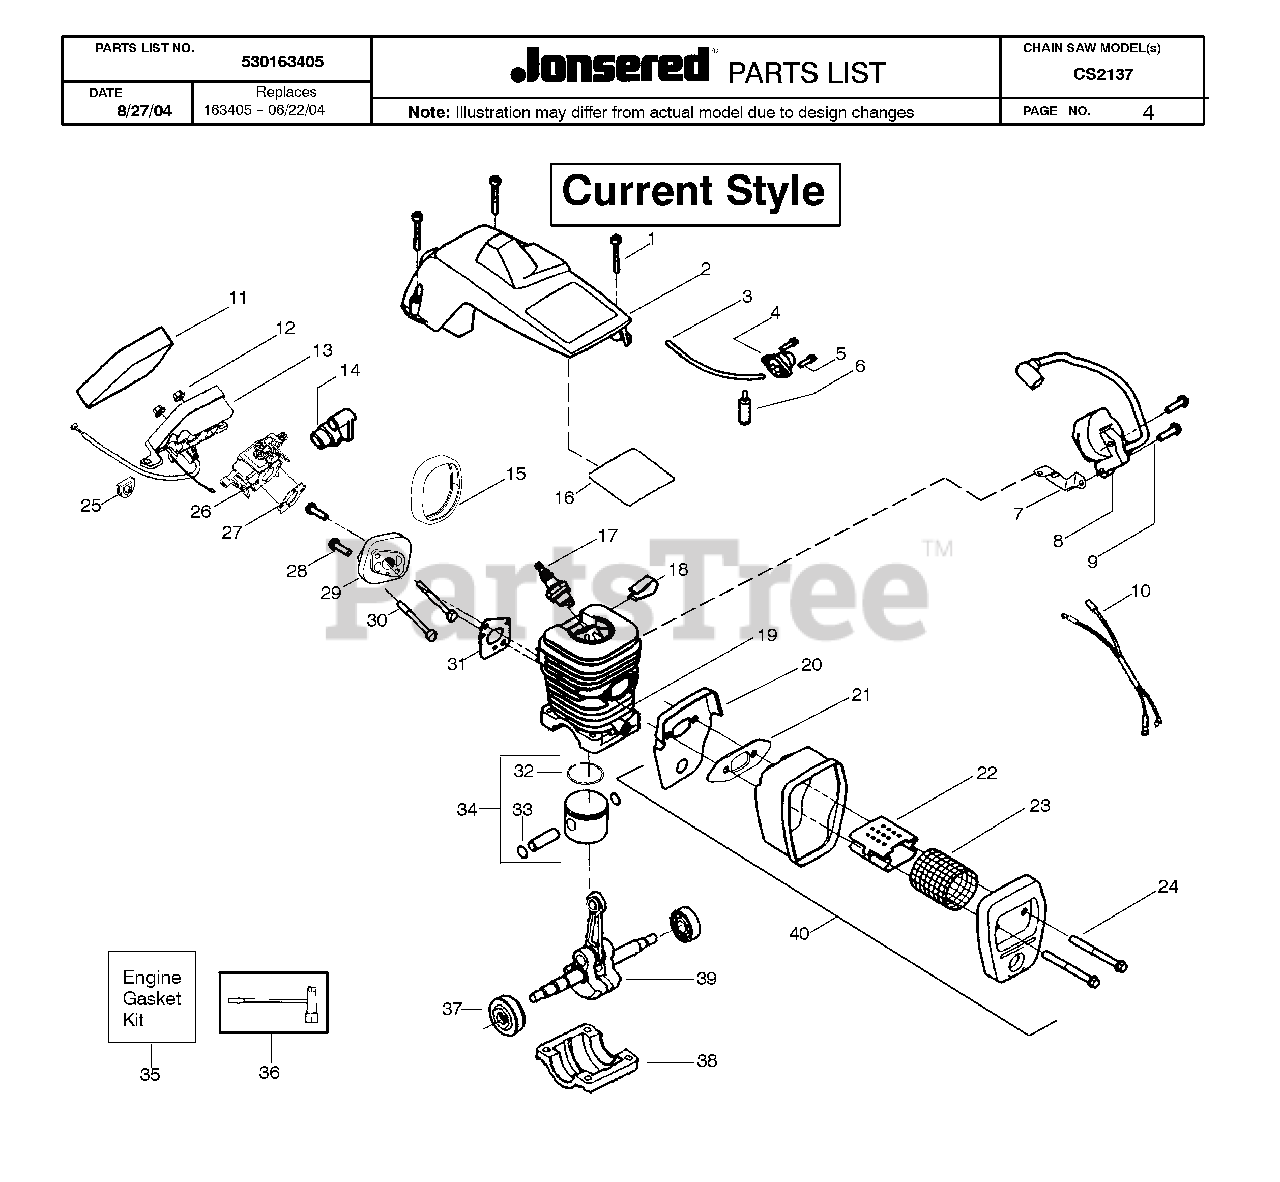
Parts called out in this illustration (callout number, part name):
2	CYL SHIELD ASSY
6	FUEL PICK-UP ASSY
7	GROUND STRAP
10	WIRE HARNESS ASSY
11	AIR FILTER
14	GROMMET-CARB ADJUST
17	SPARK PLUG (RCJ-7Y)
22	FLAME PROTECTION
29	PARTITION
32	RING-PISTON
33	C-CLIP,PSTN PIN 36/41
36	SCRENCH
37	BEARING & SEAL ASSEMBLY
39	CRANKSHAFT
40	MUFFLER
530071820	CARBURETOR
